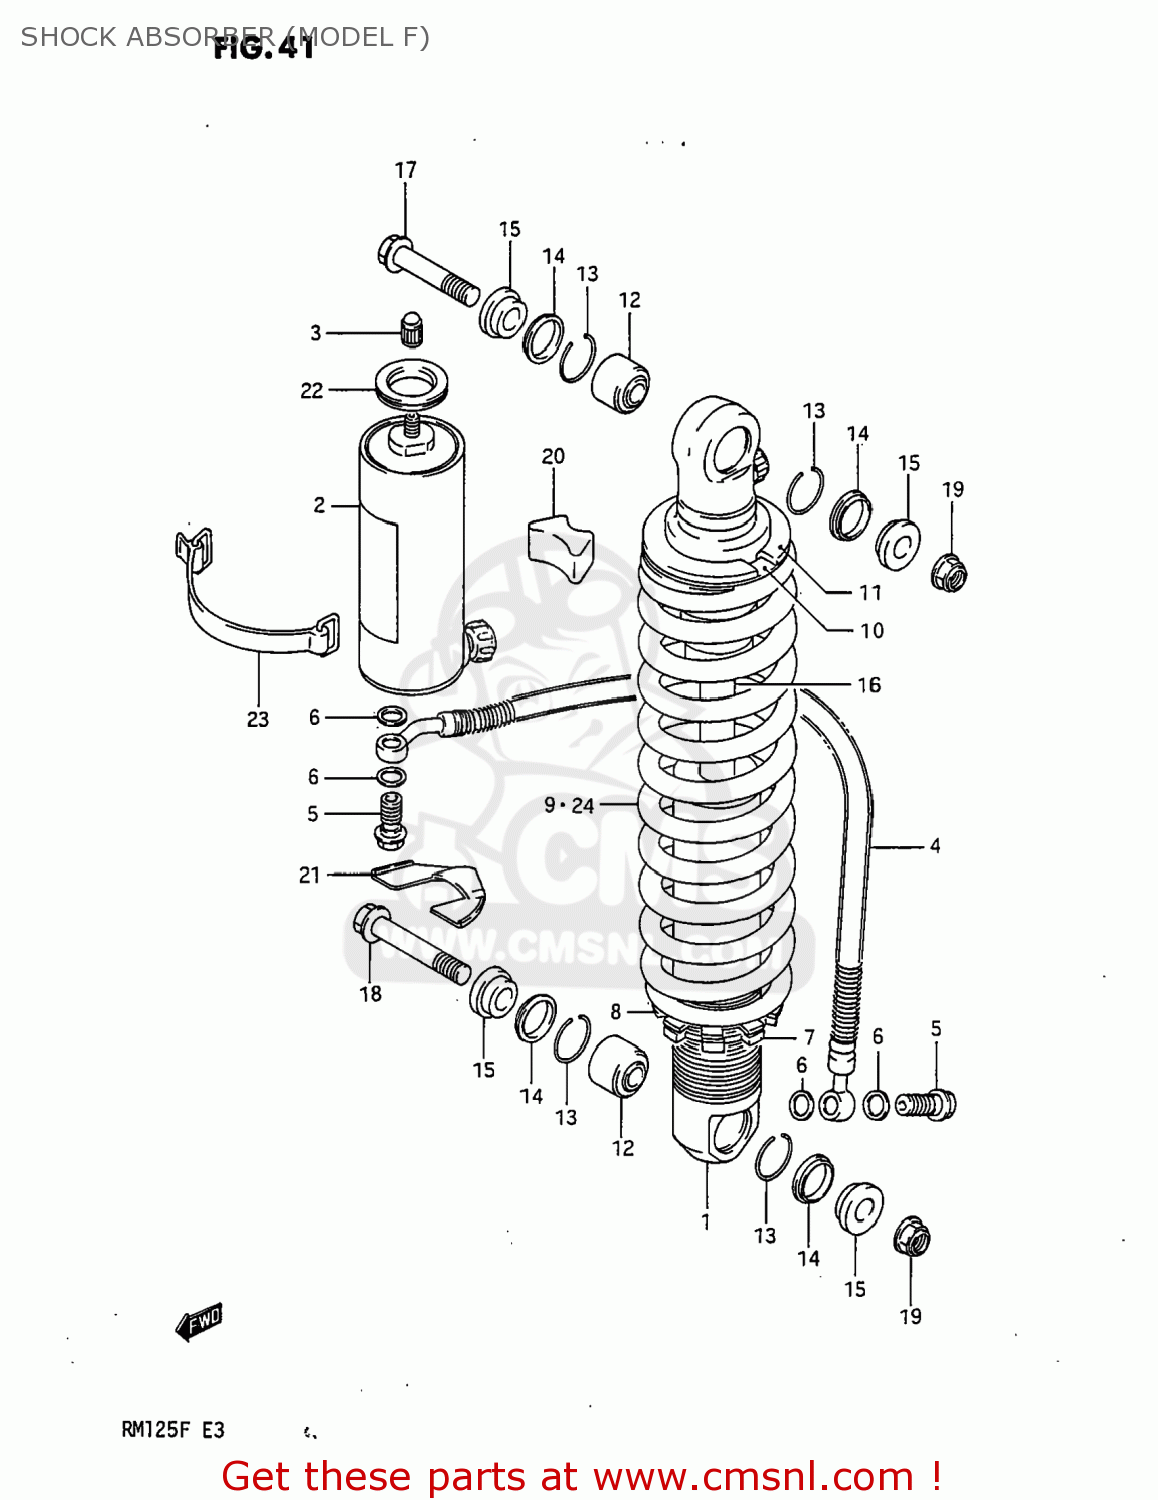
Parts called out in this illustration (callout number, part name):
1	ABSORBER ASSEMBLY,REAR SHOCK
2	RESERVOIR TANK,REAR SHOCK
3	CAP
4	HOSE,REAR SHOCK ABSORBER
5	BOLT,REAR SHOCK ABSORBER
6	GASKET (NAS)
7	GUIDE,REAR SHOCK ABSORBER SPRING
8	GUIDE,SPRING
9	SPRING
10	WASHER
11	GUIDE,SPRING
12	BEARING,REAR SHOCK ABSORBER
13	RING
14	SEAL,DUST RR SHOCK ABSORBER
15	COLLAR
16	ROD,PISTON
17	BOLT,REAR SHOCK ABSORBER
18	BOLT(10X52)
19	NUT
20	CUSHION,RESERVOIR TANK
21	CUSHION,RESERVOIR TANK
22	CUSHION,RESERVOIR TANK
23	BAND
24	SPRING
